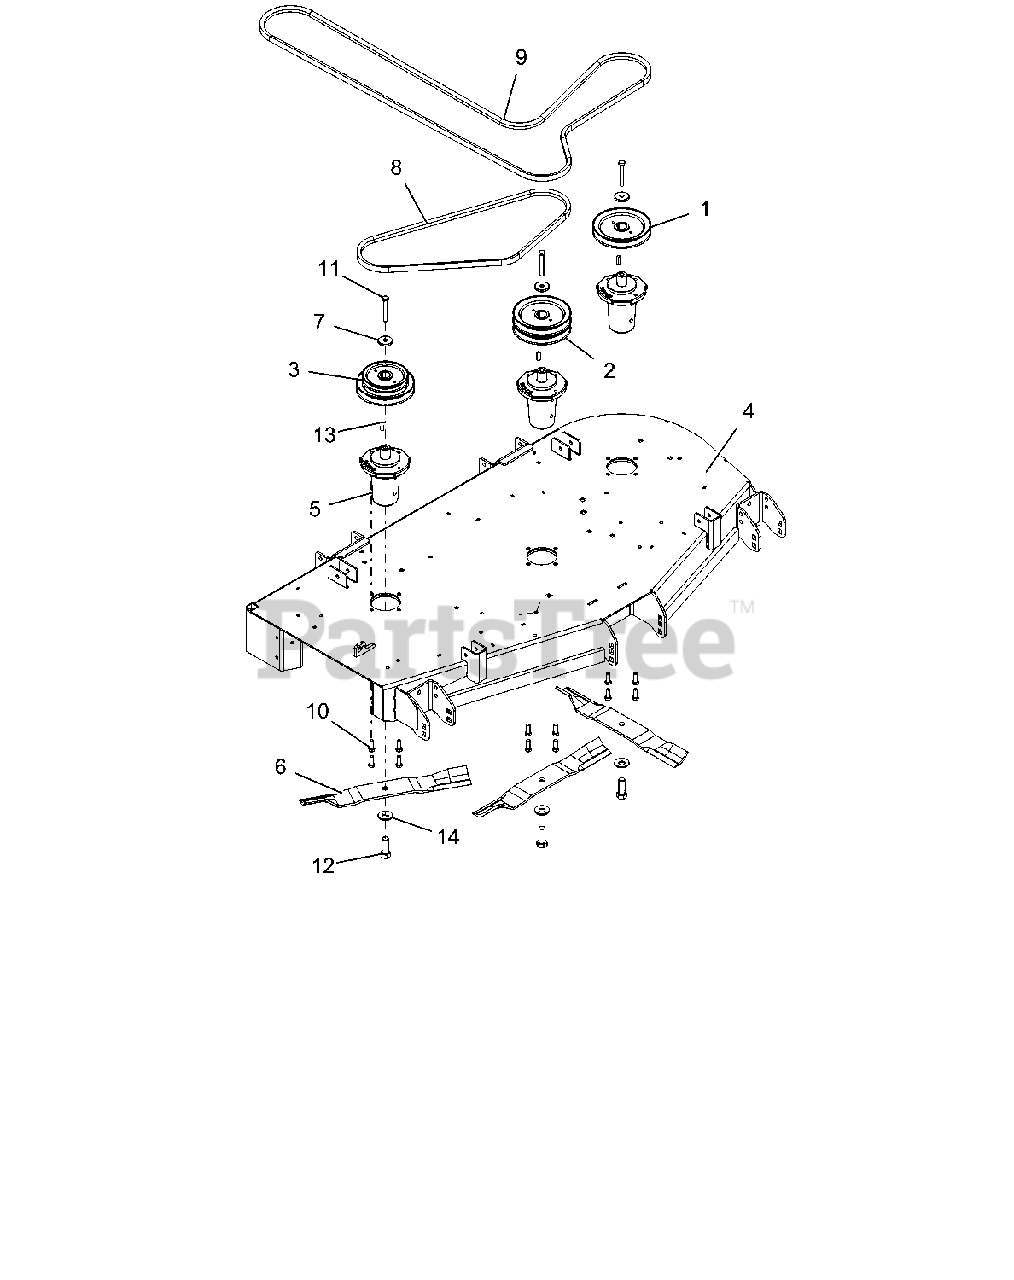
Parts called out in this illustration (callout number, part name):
1	PULLEY, SINGLE -1" ID X 6.00" OD-BLACK
2	PULLEY, DOUBLE -1" ID X 6.00" OD-BLACK
3	PULLEY, DOUBLE -1" ID X 6.00" & 4.75" OD
4	WLDMT, 52" SIDE DISCHARGE DECK
5	ASM, SPINDLE - G3500
6	BLADE, 18.00" MOVER (HI-LIFT)
7	RETAINER, SHEAVE SPINDLE
8	BELT, B 56.00 RAW COGGED
9	V-BELT, HB SECTION 123.230
10	BLT-HEX .38-16X1.00 GR5 YWZC EP30
11	BLT-HEX .38-16X2.75 GR8 YWZC
12	BLT-HEX .625-18X1.75 GR8 YWZC
13	KEY-SQ .250X.250X1.00 RC 40-50
14	WSHR, BLVL-.63X1.625X.14
